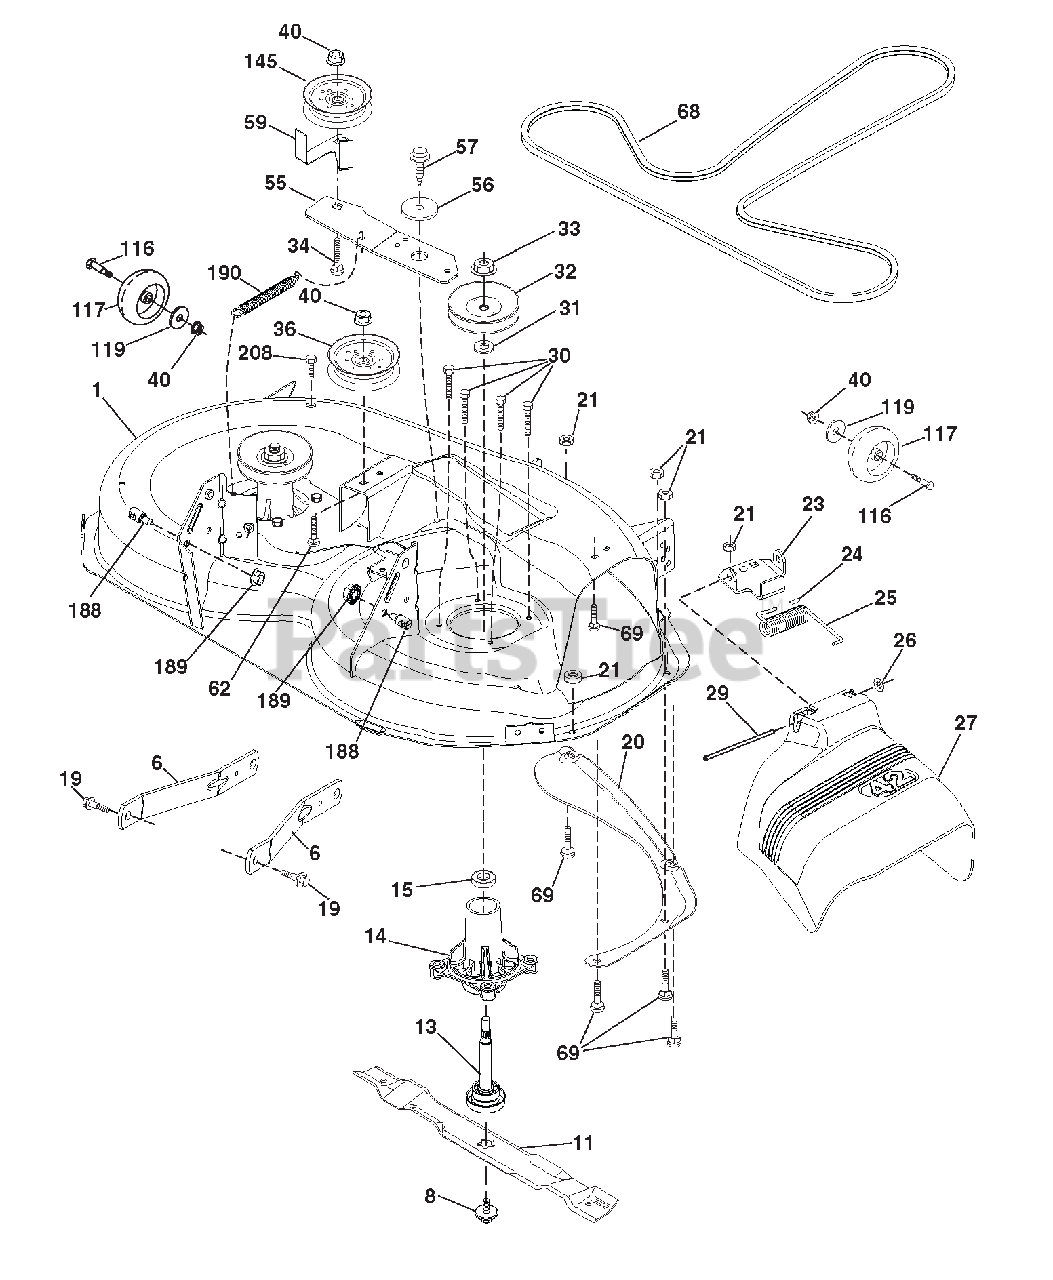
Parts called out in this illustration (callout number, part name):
1	MOWER HOUSING
6	ARM.SUSPENSION.MOWER.REAR.LD
8	BOLT/WASHER ASM.7/16-20.UNF
11	BLADE.MOWER.42"HI LIFT PREMIUM
13	SHAFT ASM.MNDRL.N/GREASEABLE38
14	HOUSING.MANDREL.4PT.SERVICE
15	BEARING.BALL.MANDREL
19	BOLT.SHOULDER
20	BAFFLE.VORTEX.42.STD/HEAVY DTY
21	Nut, Hex, Crownlock 5/16-18
23	BRACKET.DEFLECTOR.38/42"2005
24	CAP.SLEEVE..80X.112.BLK.MOWER
25	SPRING.TORSION.DFL.38/42/46.GR
26	NUT.PUSH.PHOS.& OIL
27	SHIELD.DEFLECTOR.
29	ROD.HINGE.42/46"
30	SCREW.THD ROLL.DOD PT.HEX
31	WASHER.SPACER.MANDREL
32	MANDREL.PULLEYS.42,44,50
33	NUT.FLANGE.LOCK.TOP
34	BOLT.CARR.SH.3/8-16X1-1/2.GR5
36	PULLEY.IDLER.4.50.RAW
40	Nut, Hex, Flangelock 3/8-16
55	IDLER.ARM
56	SPACER.RETAINER
57	SCREW.3/8-16X1.SMGML.TAP/R.BLK
59	GUARD.TUV.IDLER
62	BOLT.RD.HD.SQ.NK.3/8-16UNC X 2
68	V-Belt, 42" Mower
69	BOLT.RDHD.SQNK.5/16-18 X 5/8
116	BOLD SHLD "A" 2.41 "B" 1.66
117	WHEEL.GAGE.HALF.SPOKED
119	Washer 3/8 x 7/8 x 14 Ga.
145	PULLEY.IDLER 48"PRIMARY
188	STUD.FASTNER.W/'D'ANTI-ROTATIO
189	Nut, Lock Hex Flange 5/16-18 u
208	SCREW.THDROL.3/8-16X1/2.TYT.BL
